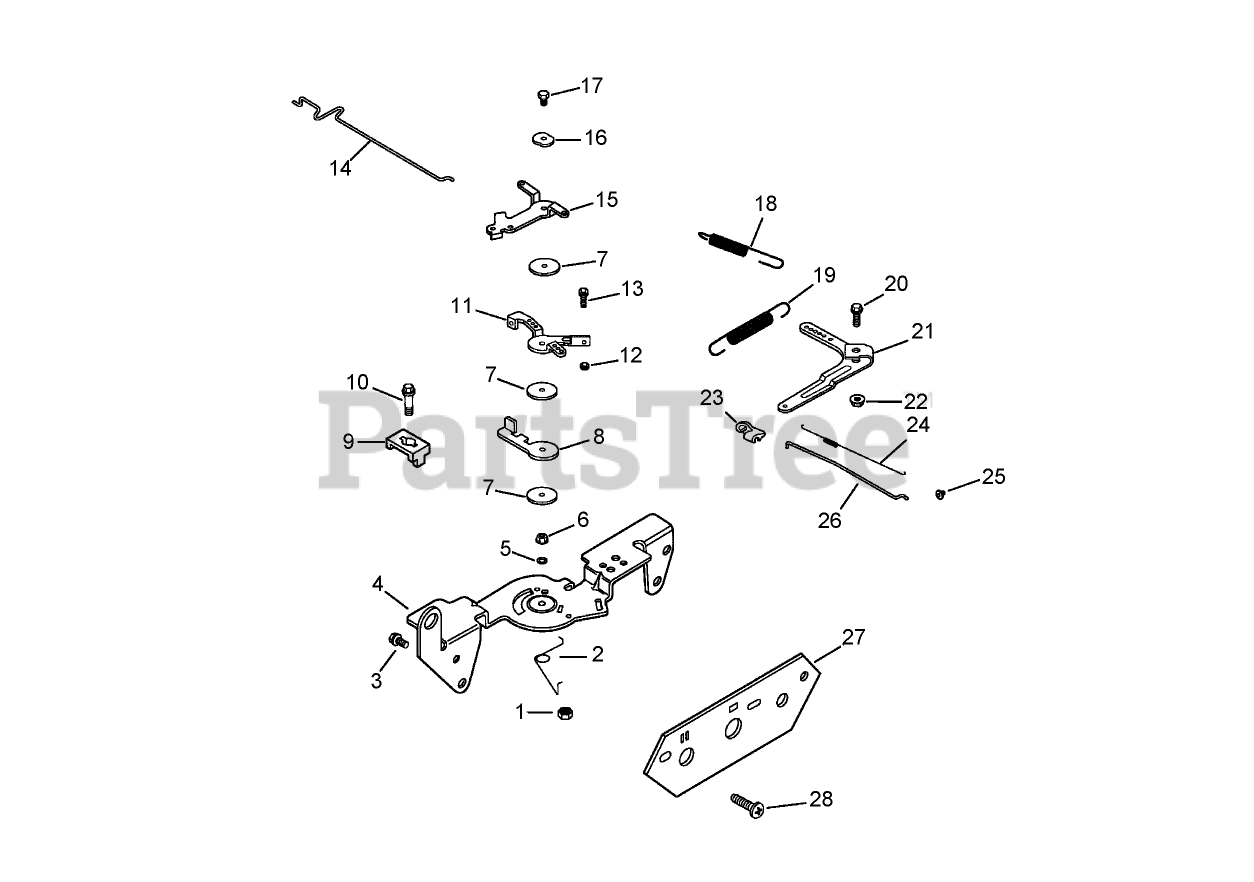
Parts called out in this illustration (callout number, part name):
1	NUT-LOCK (M5X.8)
2	SPRING-RETURN, CHOKE
3	SCREW-FLANGE, THREAD FORMING (M6X1.0X16)
4	Bracket-Control
5	Washer-Lock (.25)
6	Nut-HF (M5x0.8)
7	WASHER-FLAT (5.5MM)
8	Lever-Actuator, Throttle
9	CLAMP-CABLE
10	SCREW-FLANGE, THREAD FORMING (M5X0.8X16)
11	Lever-Control, Throttle
12	NUT (M4X0.7)
13	SCREW-SLOTTED HEAD (M4X0.7X25)
14	Linkage-Choke
15	LEVER-CHOKE
16	WASHER-SPRING (1/4)
17	SCREW-FLANGE, THREAD FORMING (M5X.8X20)
18	Spring-Limiter, Throttle
19	Spring-Governor
20	BOLT-SQ NECK, RD HD (M6X1.0X25)
21	Lever-Governor
22	NUT-FLANGE (M6X1.0)
23	BUSHING-RETAINING, LINKAGE
24	SPRING-LINKAGE
25	BUSHING-LINKAGE, THROTTLE
26	Linkage-Throttle
27	PANEL-CONTROL, FRONT
28	SCREW-PPH (11-16X3/4)
